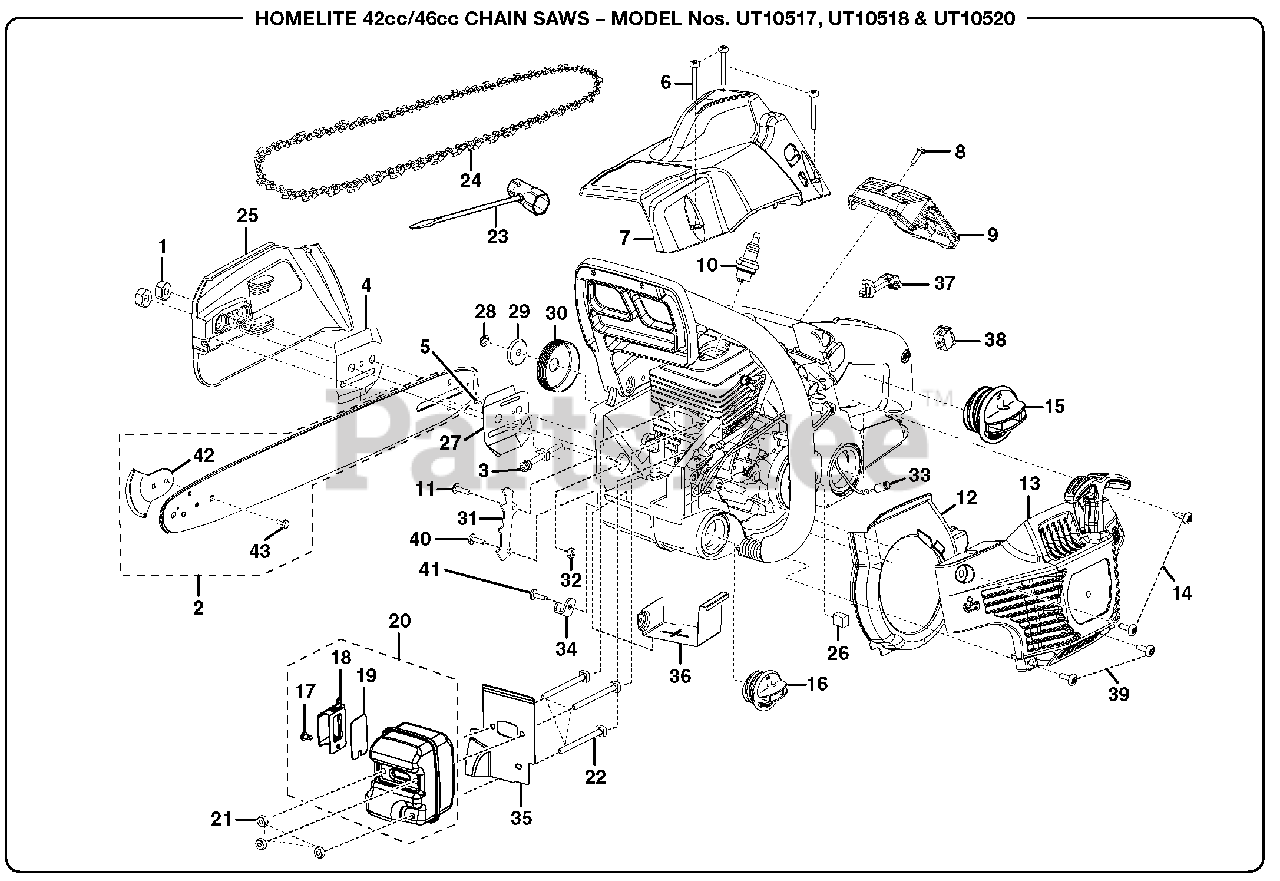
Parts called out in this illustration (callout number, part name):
1	Guide Bar Nut (5/16-18)
2	Guide Bar (18 in. with SAFE-T-TIP) (Includes Key Nos. 42, 43)
3	Guide Bar Adjustment Screw
4	Outer Guide Plate
5	Screw (6-19 x 1/2 in. T.F.)
6	Screw (10-16 x 1-1/2 in. Special)
7	Top Cover, Black
8	Screw (8-16 x 16 mm Torx T.F.)
9	Air Filter Cover
10	Spark Plug (Champion RCJ6Y)
11	Screw (10-24 x 5/8 in. Torx Pan Hd.)
12	Fan Housing Baffle
13	Starter Cover Assembly
14	Screw (10-14 x 5/8 in., Truss Hd.)
15	Fuel Cap Assembly
16	Oil Cap Assembly
17	Screw (8-32 x 5/16 in.)
19	Spark Screen
20	Muffler Assembly (Includes Key Nos. 17-19)
21	Lock Nut (10-32)
22	Muffler Bolt (Square Hd.)
23	Combination Wrench
24	Chain (.375 x 62 link, 18 in.)
25	Chain Cover Assembly
26	Pre-Filter
27	Inner Guide Plate
28	E-Ring
29	Cupped Washer
30	Sprocket Drum and Bearing Assembly (.375 chain)
31	Spike Bar
32	Lock Nut (10-24)
33	Fuel Filter
34	Chain Catcher
35	Muffler Gasket
36	Heat Shield
37	Choke Lever, Yellow
38	Ignition Switch
39	Screw (10-14 x 7/8 in., Truss Hd.)
40	Screw (10-24 x 1/2 in.)
41	Screw (10-14 x 1/2 in.)
42	Safety Tip
43	Screw (Hex Head)
